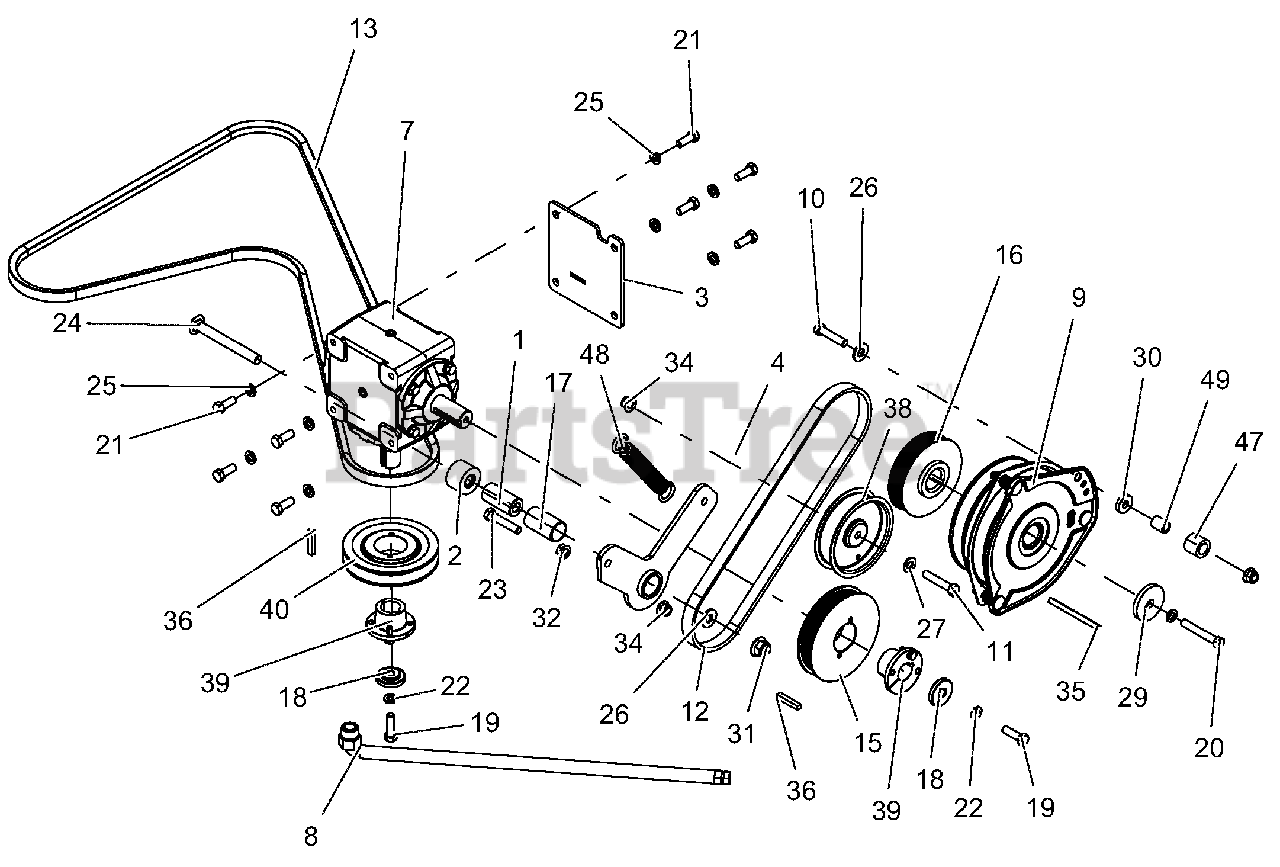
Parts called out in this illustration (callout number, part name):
1	BSHG, SPCR .502X.997X2.03
2	SPCR, PT400 DIESEL IDLER ARM
3	WLDMT, GEARBOX SUPPORT-BLACK
4	WLDMT, IDLER ARM-BLACK
7	GEARBOX, 90 1.0:1.0
8	HOSE, ASM DIESEL OIL DRAI N
9	CLUTCH, DIESEL REVERSE MOUNT
10	BLT-HEX .38-16X1.75 GR5 YWZC
11	BLT-HEX .38-16X2.00 GR5 YWZC
12	BELT, PVK 5 RIB
13	BELT, 5L RAW EDGE
15	SHEAVE, POLY -V 4.65 X 1.00
16	SHEAVE, POLY -V 4.125 X 1.125
17	BSHG, 1.00X1.125X1.937
18	RETAINER, SHEAVE SPINDLE
19	BLT-HEX .38-16X1.25 GR5 YWZC
20	BOLT, HEX 3/8-24 x 2.50 GR5 YZ EP80
21	BLT-HEX .38-16X1.00 GR5 YWZC
22	@WSHR-LK .38X.094 REG YWZC
23	BLT-HEX .38-16X2.00 GR8 YWZC
24	BLT-RDHDSQNK .50-13X4.50 G5 YWZC
25	WSHR-LK .38X.094 REG YWZC
26	WSHR-FL-STL.
27	WSHR-FL-STL.406X.812X.065 YWZ
29	WSHR-FL-STL .469X2.00X.25 YWZC
30	WSHR-FL-STL .406X1.00X.188 YWZC
31	NUT-LK-NYL-FLG .50-13 YWZC
32	NUT-SPNLK-FLG .375-16 YWZC
34	NUT-LK-NYL-FLG .38-16 YWZC
35	KEY, SQ .25 x 3.50 x .25 SAE
36	KEY, SQ .25 X .25 X 1.25
38	PULLEY, IDLER 4.00 X .375
39	BSHG, TAPER LOCK 1" SHAFT
40	SHEAVE, TAPER BUSHING
47	BUMPER, RUBBER .62 X 1.0 X .88 LG
48	SPRG, EXTENSION
49	BUSH., S .407X.625X.813 ST REVA
